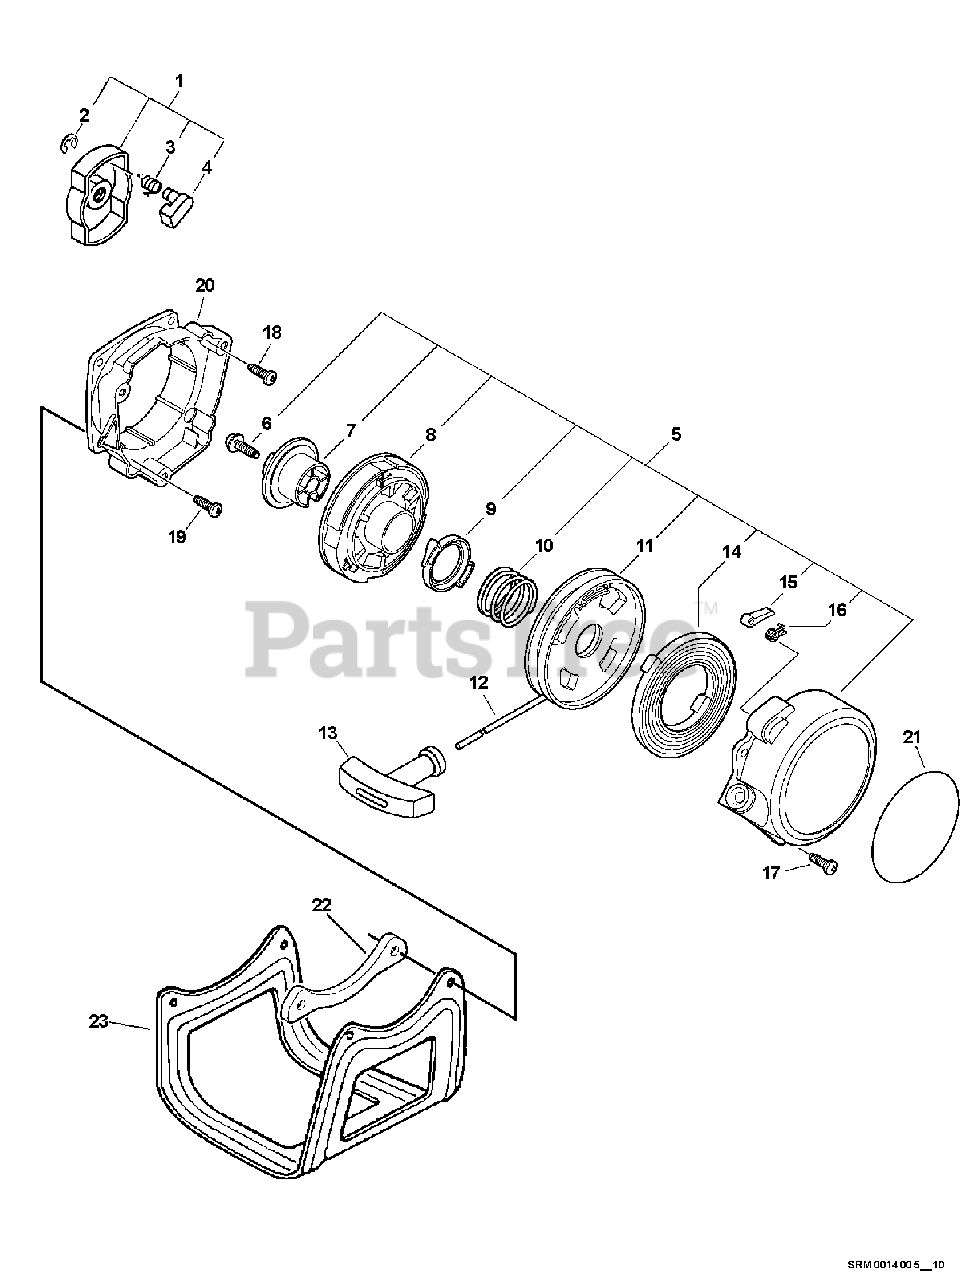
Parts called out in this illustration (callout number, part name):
1	STARTER PAWL ASSY
2	PAWL, STARTER
3	SPRING, RETURN
4	E-RING 4
5	STARTER ASSY
7	PLATE, CAM
8	SPRING ASSY
9	PAWL, STARTER
10	SPRING, RETURN
11	PULLEY, STARTER
12	ROPE, STARTER
13	GRIP, STARTER
14	SPRING, RECOIL
15	PAWL, STARTER
17	SCREW, TAPPING 5×20
18	BOLT 4×16
19	BOLT 4×20
22	PLATE, EYE
23	GUARD, FUEL TANK
